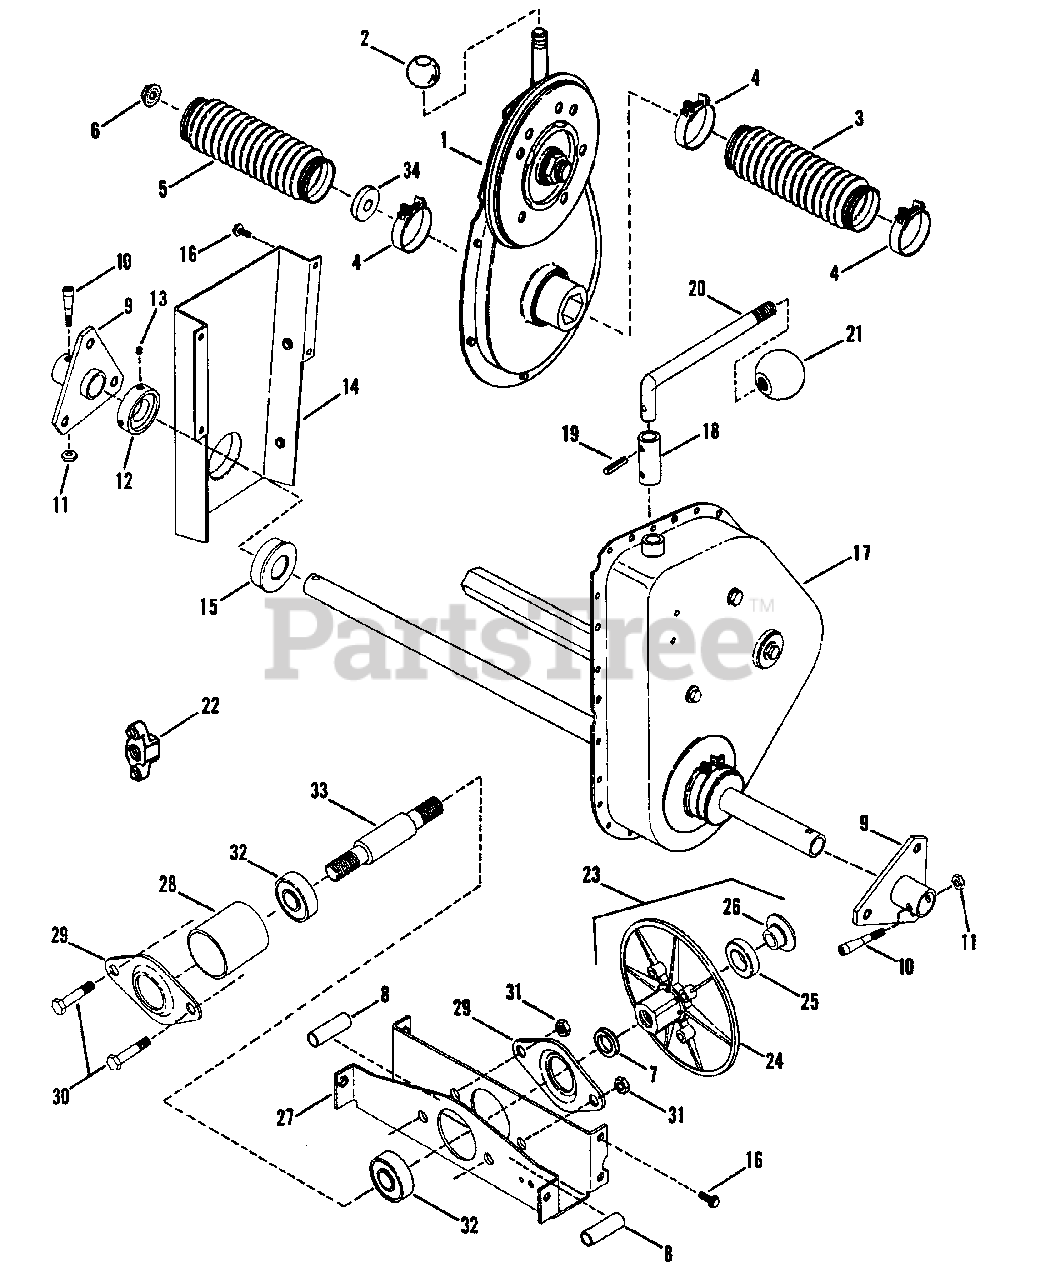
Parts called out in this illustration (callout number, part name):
1	PRIMARY CASE
2	BUSHING, Primary Clutch
3	BOOT, Left Side Oil seal
4	CLAMP, Boot
5	BOOT, Right Side Oil Seal
6	NUT, 3/8-16 Hex Flange Lock
7	WASHER, Shim
8	SPACER
9	HUB, Rear Wheel
10	BOLT, Tapered
11	NUT, 5/16-24 Hex Lock
12	LOCK-COLLAR
13	SETSCREW, 5/16-18 x 5/16"
14	ASSEMBLY, Axle Support
15	BEARING, Ball
16	SCREW, 5/16-18 x 5/8" Hex Washer Self-Tap
17	ASSEMBLY, Transmission
18	COUPLING, Shift Lever
19	ROLL-PIN, 3/16 x 3/4"
20	LEVER, HI-LO Shifter
21	KNOB, Shifter Ball
22	HUB, Flex Coupling
23	ASSEMBLY, Drive Disc
24	DISC, Drive
25	BEARING, Ball
26	BUTTON, Center
27	SUPPORT, BEARING
28	TUBE
29	RETAINER
30	SCREW, 5/16-18 x 4-1/4" Hex Head Cap
31	NUT, 5/16-18 Hex Center Lock Grade B or 5
32	BEARING, Ball
33	SPINDLE, Drive Disc - 6.040"
34	WASHER, Shim
